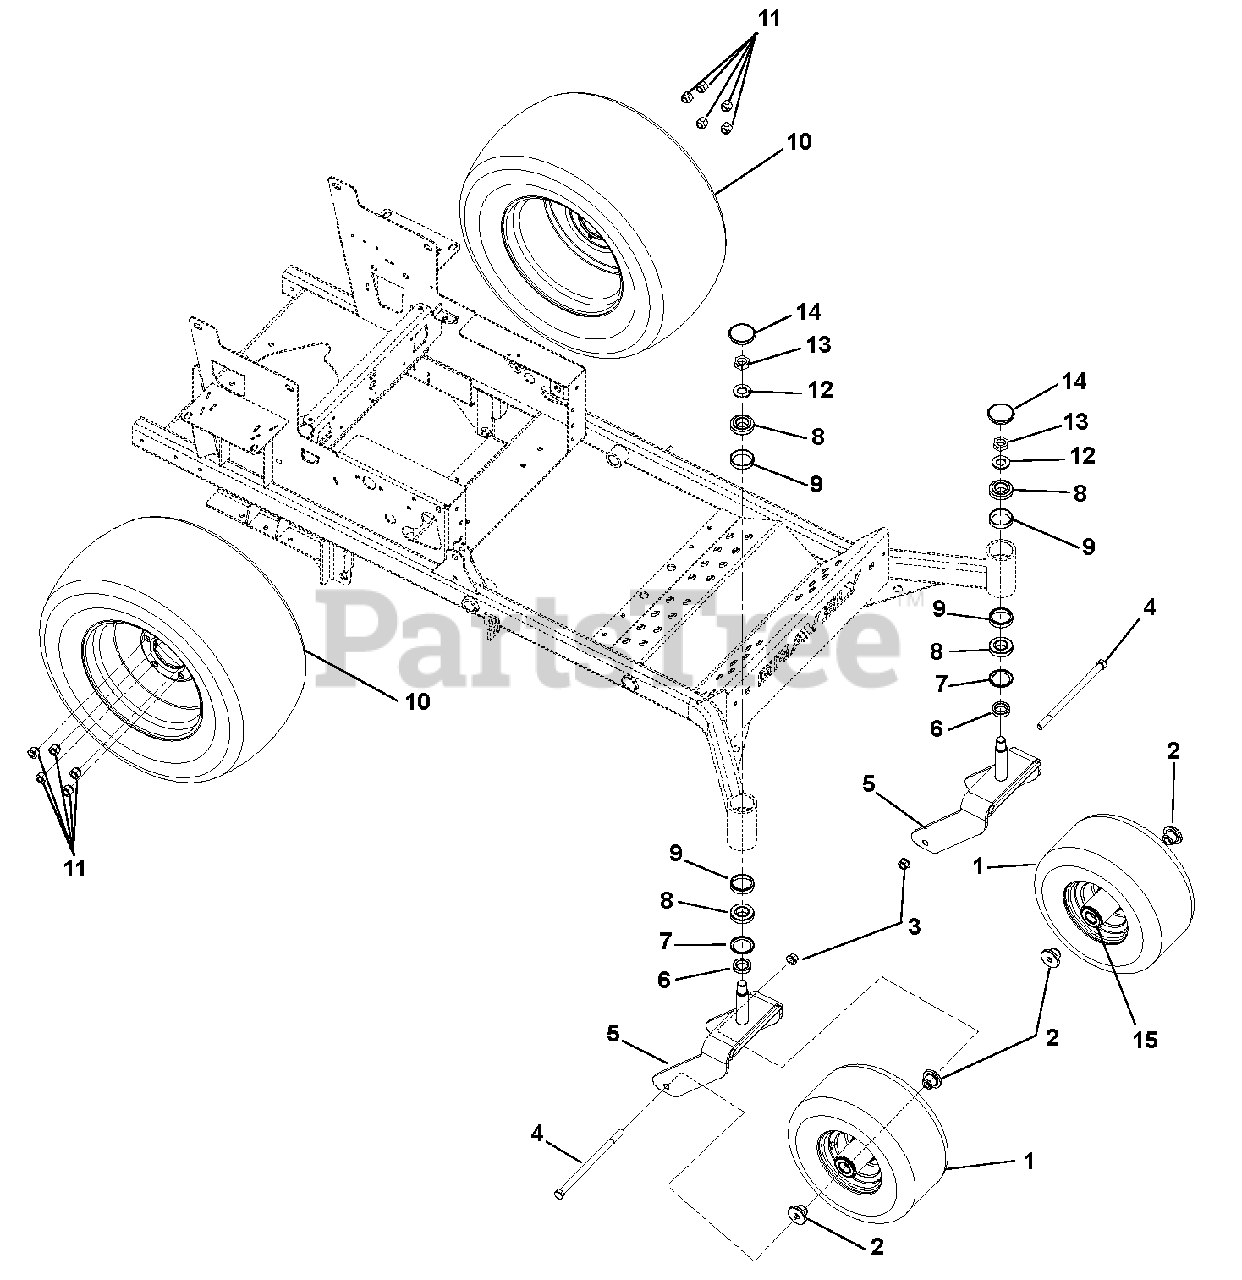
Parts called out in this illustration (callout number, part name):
1	Tire/Wheel Assembly, 13 x 6.50-6
2	Spacer, Front Wheel
3	Nut, Nyloc Flange .50-13
4	Bolt, Hex .50-13 x 9.00
6	Spacer 1.258 x 1.75 x .550
7	Seal, Oil 1.75 x 2.332 x .312
8	Bearing, Cone 1.25 x .66
9	Bearing, Cup 2.328 x .465
10	Tire/Wheel Assembly, 23 x 10.50-12
11	Nut, Wheel .50-20 13/16 Across Flats, Automotive Type
12	Washer, Flat Steel .812 x 2.00 x .148
13	Nut, Jam Center Lock .75-16
14	Cap, Dust
15	Bearing, 25 mm ID x 52 mm OD x 15 mm
